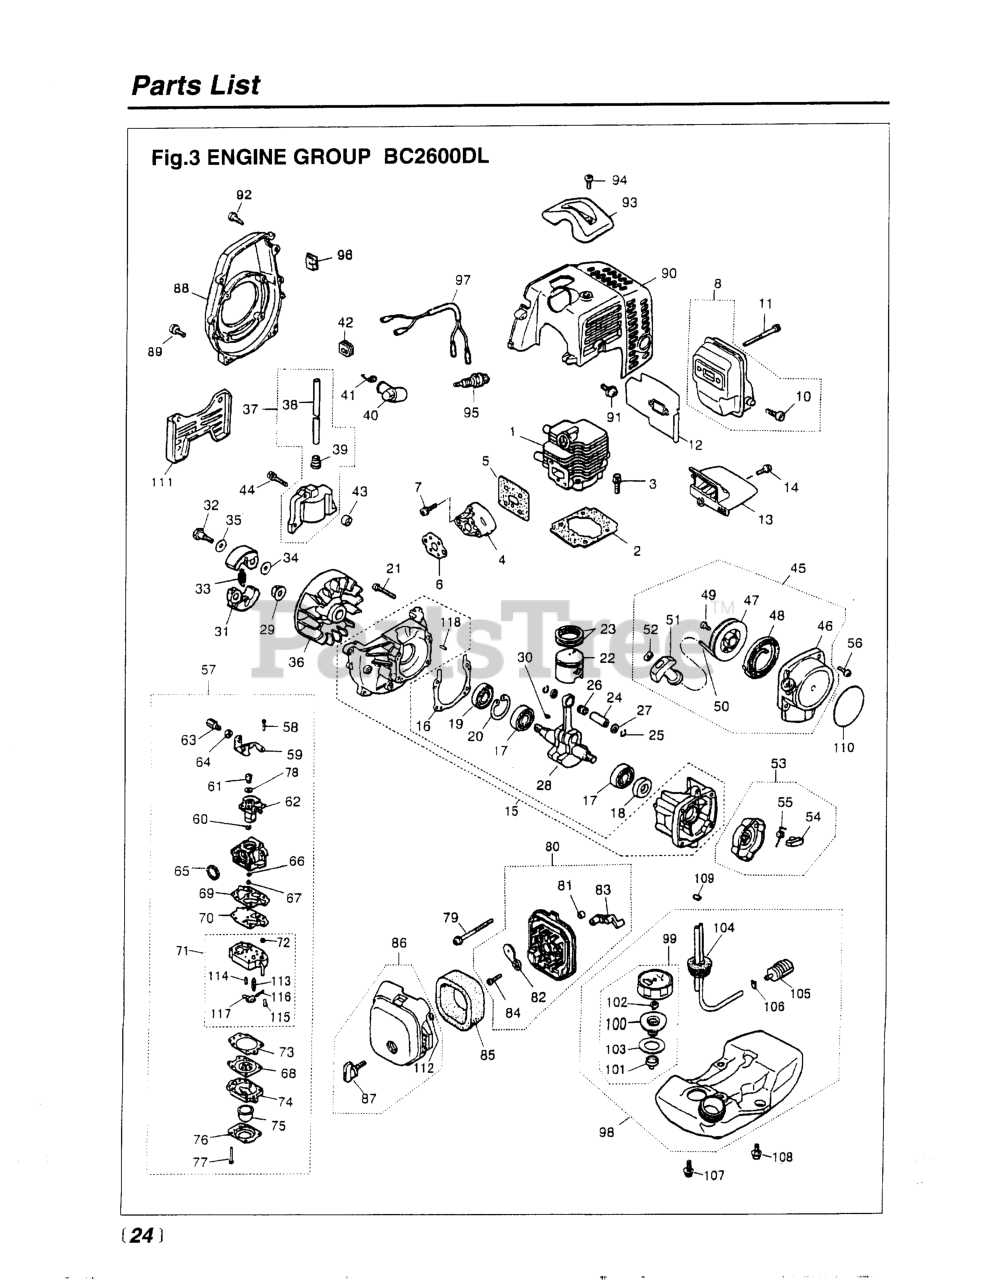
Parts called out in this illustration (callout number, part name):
1	CYLINDER
3	BOLT, M5 X 22
4	INSULATOR (USE -13163)
7	SCREW, M5X20 (RPLS.1400-75510)
8	MUFFLER ASSY (RPLS 5501- )
10	ARRESTER (RPLS 5850-15140)
11	BOLT, M5 x 50
14	SCREW, M4 X 16
15	CRANKCASE
17	BEARING
18	SEAL, OIL (RPLS 1100-21210)
19	SEAL, OIL (RPLS 1140-21220)
20	RING, SNAP, M28 x 1.2
21	BOLT, M5 X 30
22	PISTON
23	RING, PISTON
24	PIN, PISTON
25	RING, SNAP (RPLS 1101-41320)
27	WASHER
28	CRANKSHAFT (RPLS 1850-42000)
30	KEY
31	SHOE (RPLS 1100-51114)
32	BOLT
33	SPRING, CLUTCH (RPLS-51220)
34	WASHER, FLAT (USE 182303)
36	ROTOR
37	COIL ASSY (RPLS 5500-71200)
38	CORD
39	CAP
41	SPRING
42	GROMMET
43	SPACER (RPLS -71260)
44	BOLT
45	RECOIL ASSEMBLY
46	CASE
47	REEL
48	SPRING, SPIRAL
49	SCREW (RPLS -75150)
51	KNOB
52	PLATE, STOPPER
53	PULLEY ASSY (RPLS -75210)
54	RATCHET (RPLS 1850-75220)
55	SPRING, RETURN
56	SCREW, M4 X 16
57	CARBURETOR (WYJ-117)
58	SCREW
60	RING
61	SWIVEL
62	VALVE ASSY
63	SCREW, CABLE ADJUSTER
64	NUT, CABLE ADJUSTER
65	RING, PACKING
66	RING, O
67	JET
68	DIAPHRAGM (USE 4810-81260)
69	GASKET, PUMP
70	DIAPHRAGM
71	BODY, PUMP
73	GASKET, DIAPHRAGM
74	BODY, PURGE
75	PUMP, PRIMING
76	COVER, PUMP
77	SCREW
78	WASHER
79	SCREW, M5 X 55
80	BODY-A (RPLS -82101)
81	SLEEVE
82	PLATE, CHOKE (RPLS-82130)
83	LEVER, CHOKE
84	SCREW (REPLACES 50030272)
85	ELEMENT
87	KNOB (RPLS -82220)
88	COVER, FAN (RPLS-31110)
89	SCREW, M5X20 (RPLS.1400-75510)
91	SCREW, M5 x 12
92	SCREW, HOUSING
93	GUARD, PLUG
94	SCREW,M5 X 14 (RPLS 1400-15510
97	CORD COMP (RPLS -73200)
101	HOLDER, CAP
102	VALVE (NLA WHEN OUT)
103	PACKING
104	PIPE COMPLETE
105	FILTER (RPLS 1850-85300)
106	CLIP (REPLACES 2841-31280)
107	SCREW
108	SCREW W/ WASHER
109	CLIP
110	LABEL, RECOIL (RPLS -91120)
111	STAND
112	RING
113	VALVE, INLET
114	SPRING, METERING LEVER
115	SCREW, METERING LEVER PIN
116	PIN, METERING LEVER
117	LEVER
118	PIN
